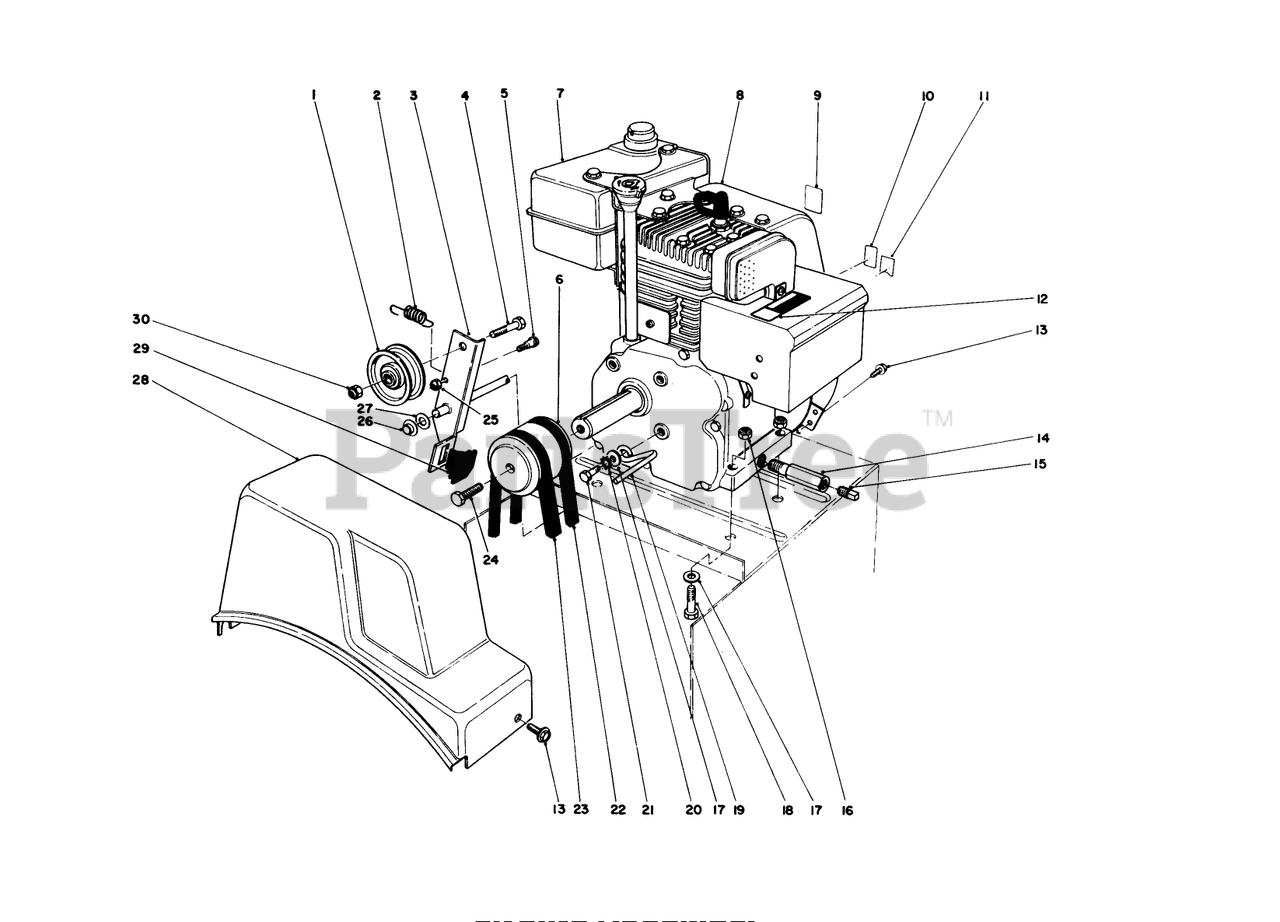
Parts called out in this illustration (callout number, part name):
1	PULLEY-IDLER
2	SPRING
4	SCREW-HH
5	BOLT-SHOULDER
6	PULLEY-ENGINE
8	Engine
13	SCREW-HWH
14	PIPE-NIPPLE
15	CAP-PIPE
16	NUT-LOCK, NI
17	WASHER-PLAIN
18	SCREW-HH
19	RETAINER-BELT
20	WASHER-LOCK
21	SCREW-HH
22	V BELT-3L, TRACTION
23	V-BELT
24	SCREW-SPECIAL
25	NUT-LOCK, CONE
26	NUT-PUSH
27	WASHER-FLAT
28	COVER-BELT
30	NUT-LOCK, CONE
